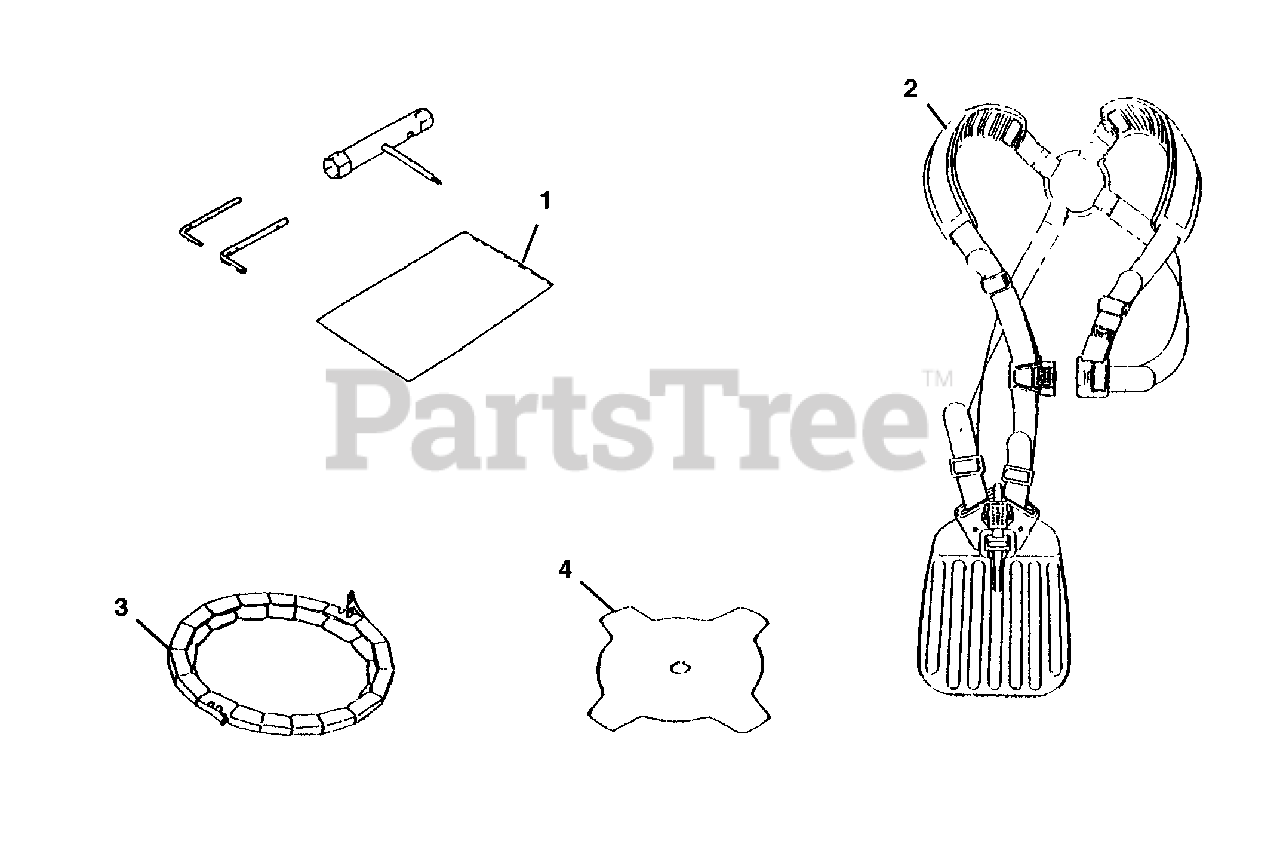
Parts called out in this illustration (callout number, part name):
1	TOOL KIT
2	SHOULDER HARNESS
3	BLADE COVER
4	BLADE CUTTER
